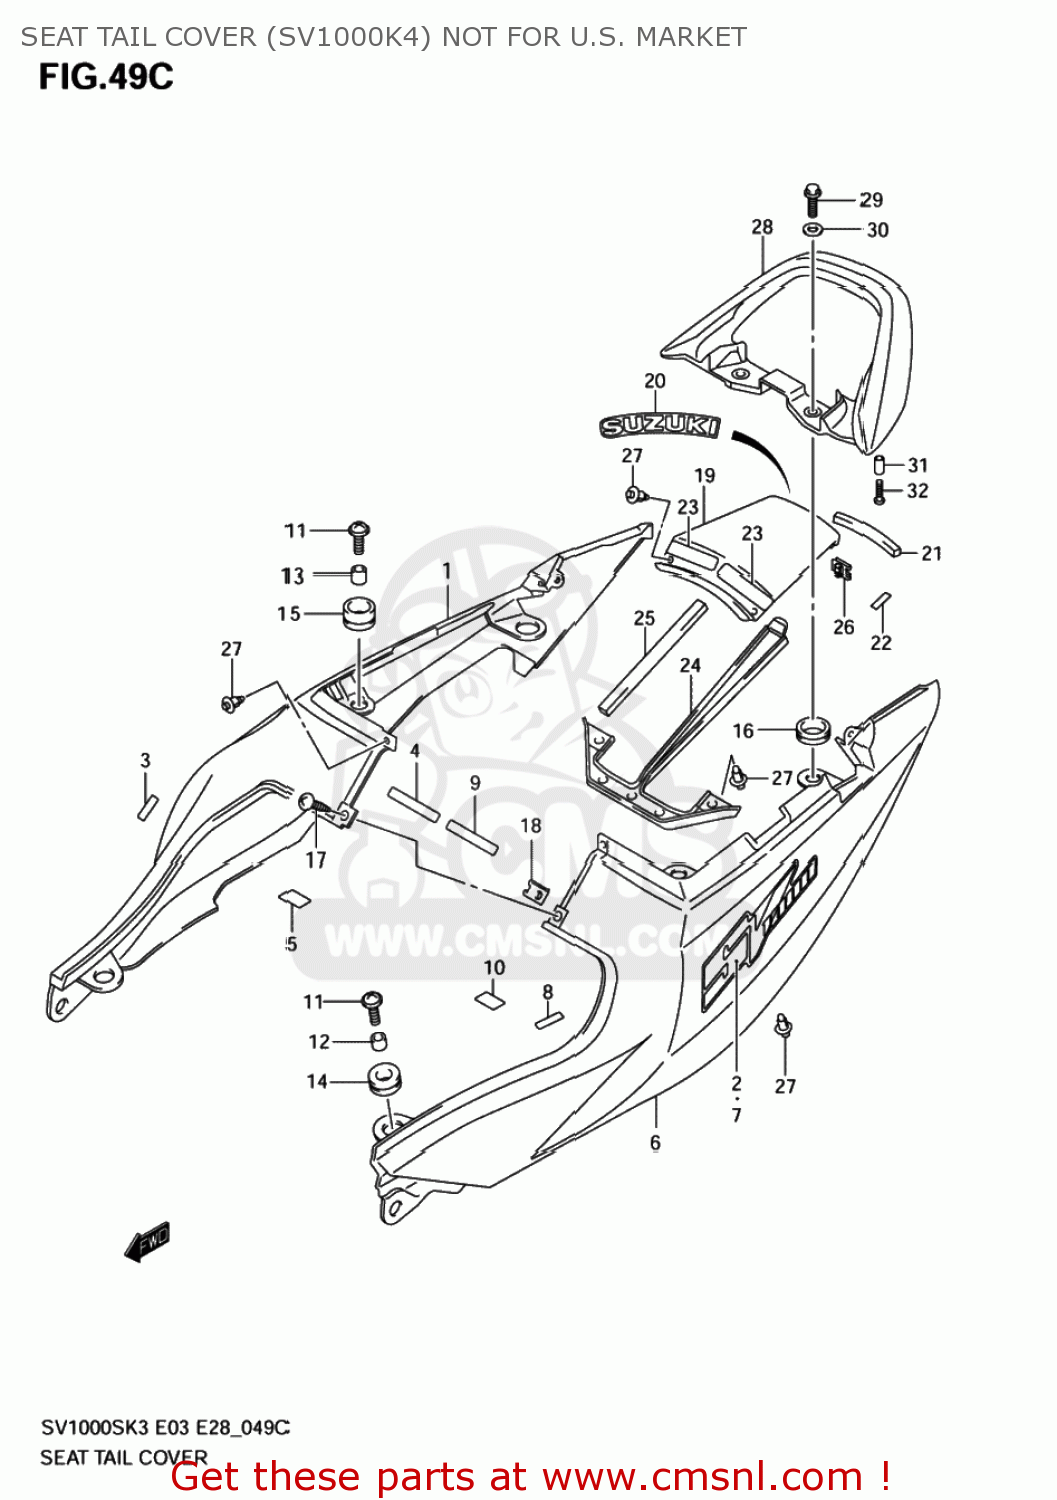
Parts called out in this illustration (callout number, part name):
1	COVER,SEAT TAIL
2	EMBLEM,SEAT TAIL COVER
3	TAPE,COVER
4	TAPE,SEAT TAIL COVER NO.2 FR
5	PROTECTOR,FRAME COVER
6	COVER,SEAT TAI
7	EMBLEM,SEAT TAIL COVER
8	TAPE,COVER
9	TAPE,SEAT TAIL COVER NO.2 FR
10	PROTECTOR,FRAME COVER
11	SCREW(6X25)
12	SPACER(6.5X10X9.4)
13	SPACER(6.5X10X9.4)
14	CUSHION
15	CUSHION,SEAT TAIL COVER CTR
16	CUSHION
17	SCREW
18	NUT
19	COVER,SEAT TAIL CTR
20	EMBLEM,SUZUKI
21	CUSHION,SEAT TAIL COVER CTR
22	TAPE,SEAT TAIL COVER
23	TAPE,COVER
24	COVER,SEAT TAIL RR
25	CUSHION,SEAT TAIL COVER
26	NUT
27	CLIP(BLACK)
28	HANDLE,PILLION RIDER
29	BOLT
30	WASHER(8.5X24X2.3)
31	SPACER(6.5X9X18)
32	SCREW(6X25)
